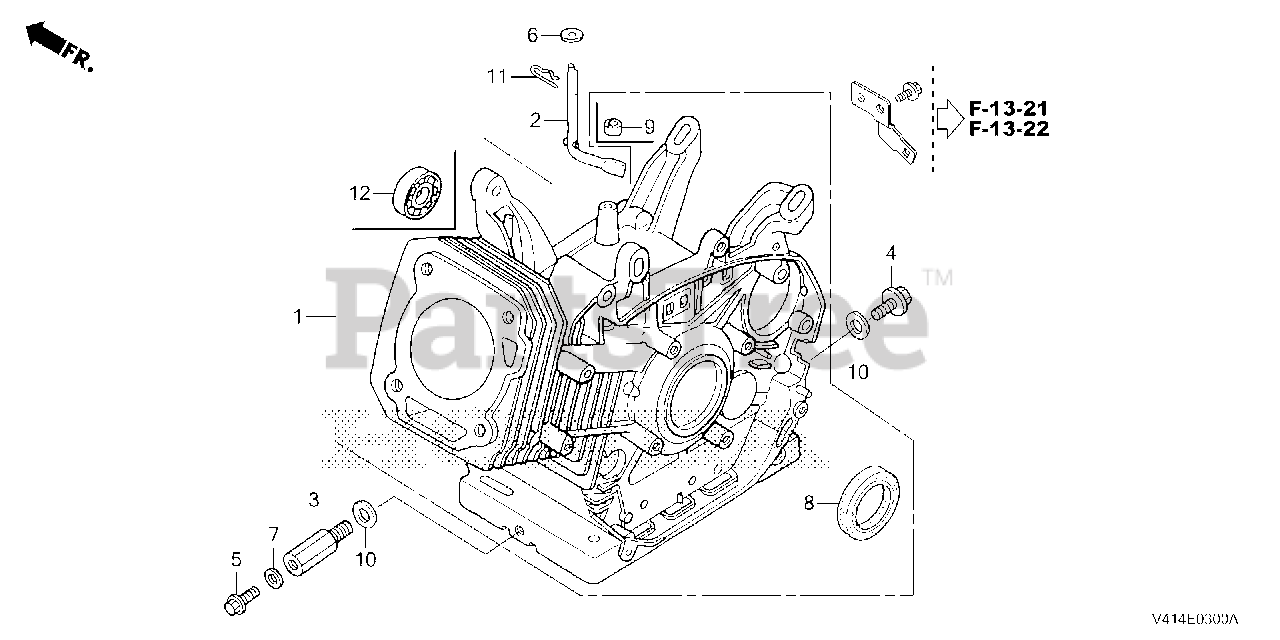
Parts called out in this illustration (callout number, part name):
1	CYLINDER ASSY.
2	SHAFT, GOVERNOR ARM
3	EXTENSION, OIL DRAIN
4	BOLT, DRAIN PLUG
5	BOLT, DRAIN PLUG
6	WASHER (8.2X17X0.8)
7	WASHER, DRAIN PLUG (10.2MM)
8	OIL SEAL (35X52X8) (NOK)
8	OIL SEAL (35X52X8)
9	OIL SEAL (8X14X5)
10	WASHER, DRAIN PLUG (12MM)
11	PIN, LOCK (10MM)
12	BEARING, RADIAL BALL (6202)
12	BEARING, RADIAL BALL (6202) (FUJIKOSHI)
